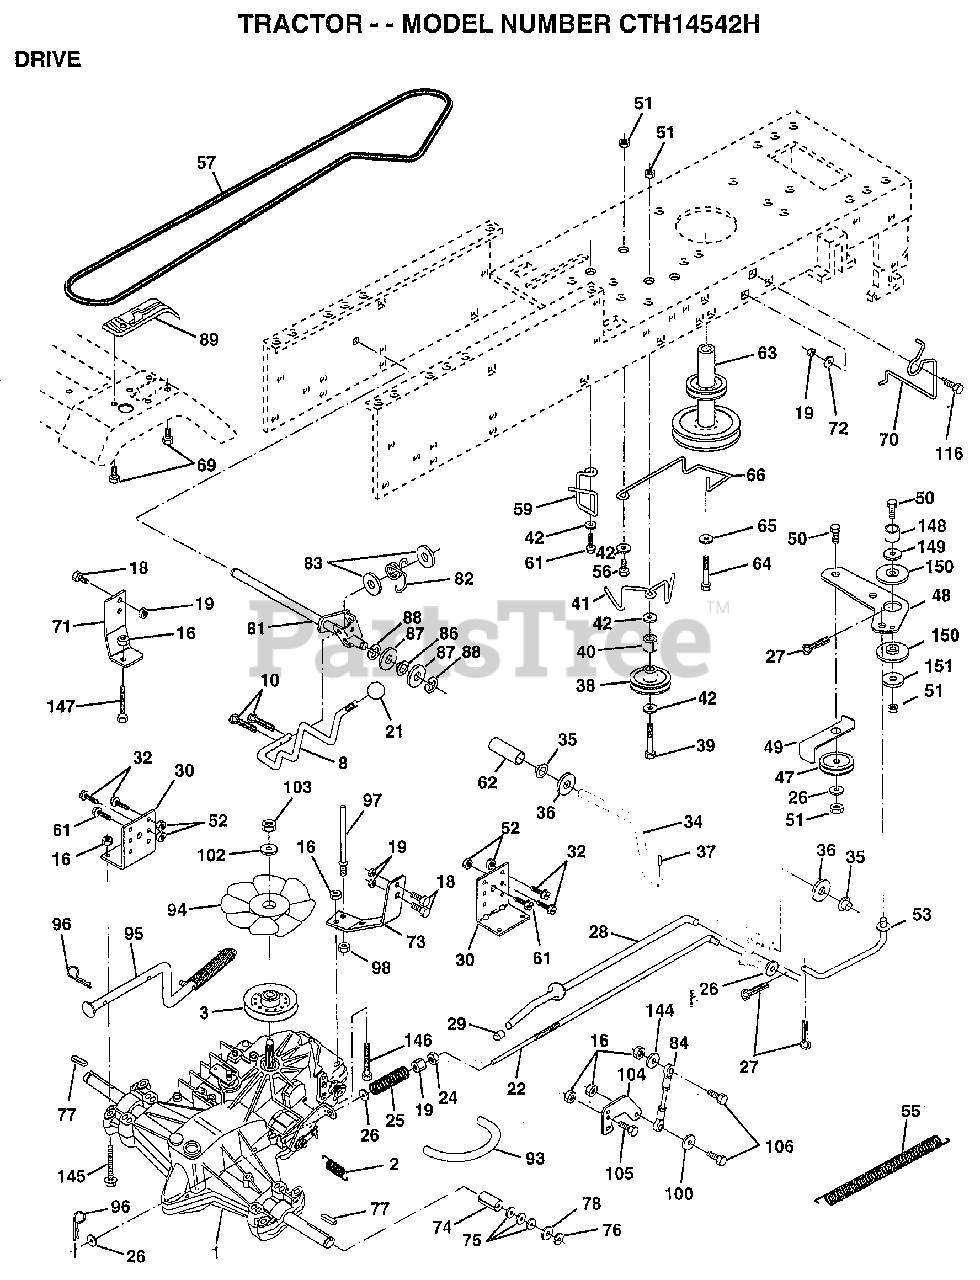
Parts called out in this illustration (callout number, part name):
1	TRANSAXLE.3100650
2	SPRING RET BRAKE
3	PULLEY.TRANSAXLE
8	ROD SHIFT FEND LT
10	PIN COTTER 1/8
16	NUT
18	BOLT
19	NUT
21	KNOB DLX BLK/BLK
22	ROD.BRAKE.HYDRO.
24	NUT
25	SPRING ROD LT
26	WASHER
27	COTTER PIN
28	ROD.BRAKE.PARK.LT
29	PLUNGER CAP T
30	TRANSAXLE MTG BKT
32	BOLT
34	SHAFT ASM-PEDAL F
35	NYLON BEARING
36	WASHER LT
38	PULLEY.IDLER.FLAT
39	BOLT
40	SPACER T
42	WASHER
48	BELLCRANK.CLUTCH
49	RETAIN BELT
53	"LINK, CLUTCH T"
55	"SPRING, RETURN LT"
57	"BELT.GD DRV 82"""
59	KEEPER BELT CNTSP
61	SCREW
62	PEDAL COVER T
63	PULLEY.ENGINE
64	BOLT
65	LOCKWASHER
66	KEEPER-BELT
69	SCREW HEXWSH H-L
70	KEEPER BELT ENG
71	STRAP TORQ LH HYD
72	WASHER
73	"STRAP-TORQUE,RH"
74	SPACER SPLIT
76	E-RING LT
77	SQUARE KEY
78	WASHER
81	SHAFT.CROS.20.HYD
82	"SPRING,TORSION"
83	WASHER
84	ROD.TIE
86	BUSHING
87	WASHER D
88	KLIP RING
93	"LINE FUEL HYD 4"""
94	"FAN 7"" HYDRO"
97	BOLT KEEPER RH
98	NUT
100	WASHER M
102	WASHER BELLEVILLE
104	ARM CONTROL HYDRO
105	SCREW CAP 5/16-18
106	BOLT
116	BOLT RDHD 3/8-16
144	WASHER
145	BOLT.HEX.FLGHD
146	BOLT.HEX.FLGHD.
147	BOLT.HEX.FLGHD
149	SPACER RETAINER
150	BUSHING.NYLON
151	WASHER
